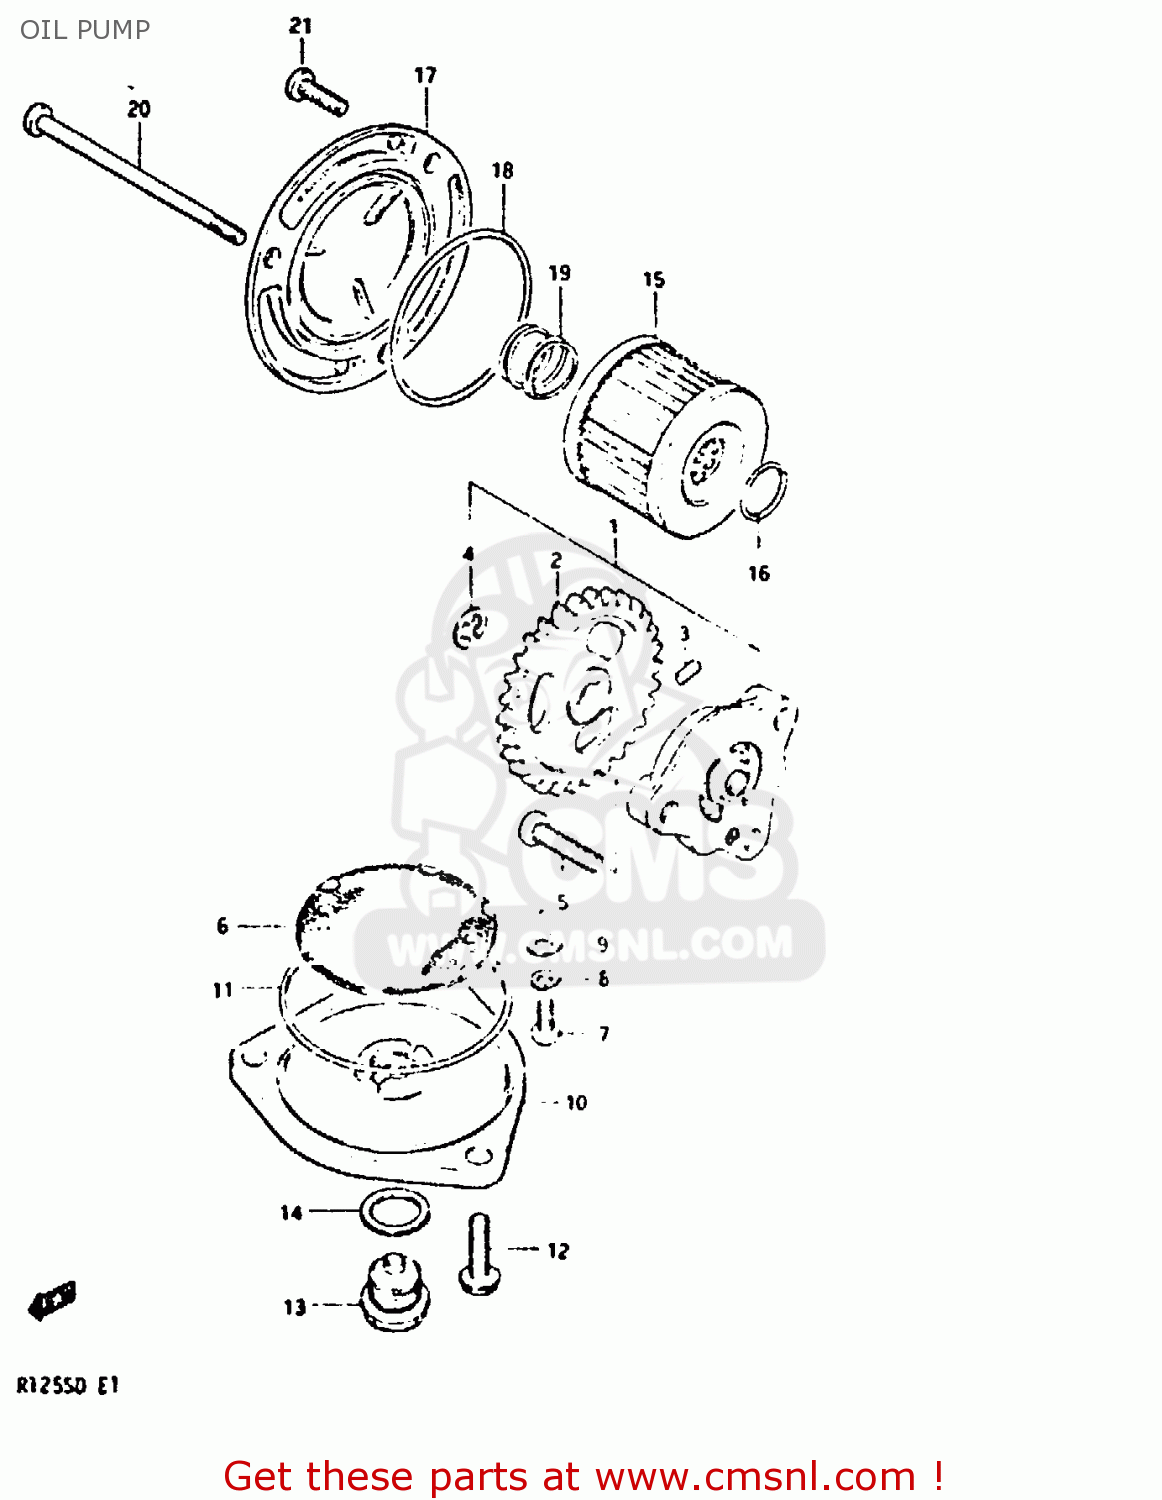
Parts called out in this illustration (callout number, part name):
1	PUMP ASSEMBLY,OIL
2	GEAR,ENG OIL PUMP DRIVEN(NT:30
3	PIN(2.5X11.8)
4	E RING 6MM
5	SCREW
6	STRAINER,ENGINE OIL
7	SCREW
8	LOCK WASHER
9	WASHER
10	CAP,OIL STRAINER
11	O RING(D:2.4,ID:60.5)
12	BOLT,REAR
13	PLUG
14	GASKET(14X19.2X2) (NAS)
15	FILTER ASSY,ENGINE OIL
16	O RING(D:1.9,ID:13)
17	CAP,OIL FILTER
18	O RING(D:2.4,ID:52.6)
19	SPRING
20	SCREW
21	SCREW
